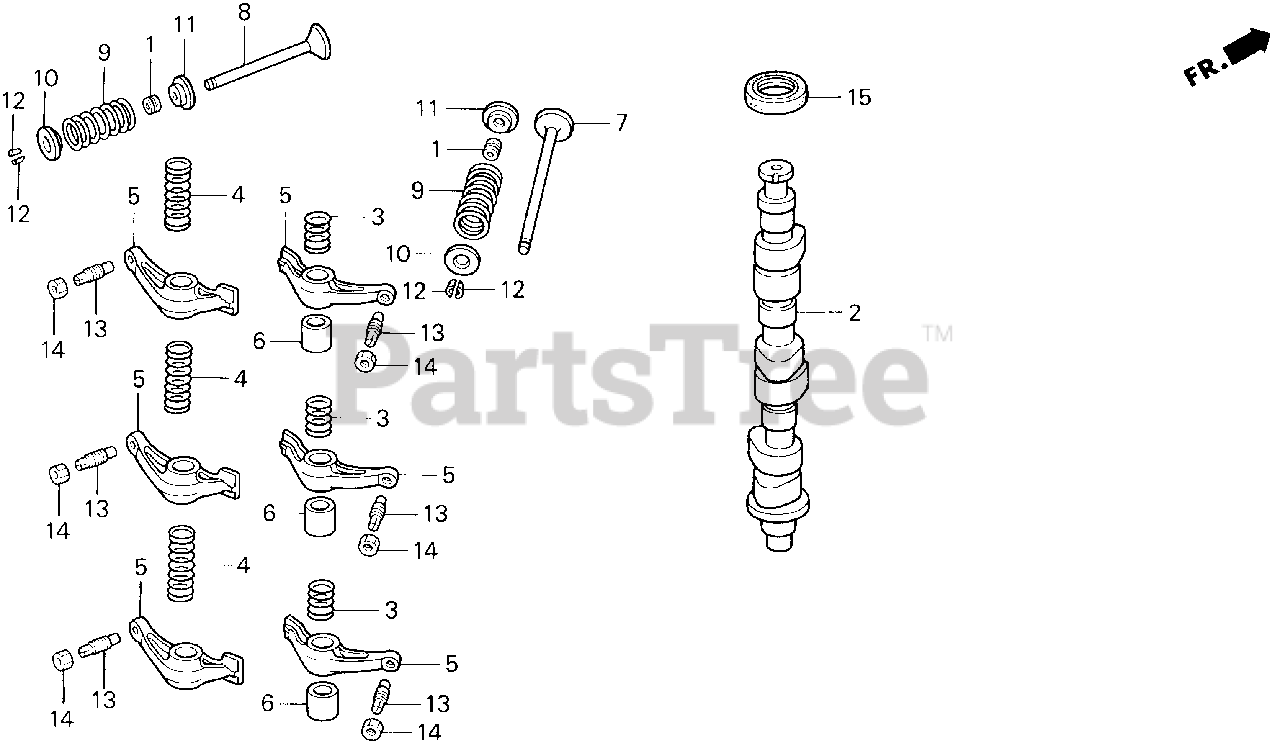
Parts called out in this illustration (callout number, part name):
1	SEAL, VALVE STEM
3	SPRING, ROCKER ARM A
4	SPRING, ROCKER ARM B
5	ARM, IN. ROCKER
6	COLLAR, ROCKER
7	VALVE, IN.
8	VALVE, EX.
9	SPRING, VALVE
9	SPRING, VALVE (CHUO SPRING)
10	RETAINER, VALVE SPRING
11	SEAT, VALVE SPRING
12	COTTER, VALVE
13	SCREW, TAPPET ADJUSTING
14	NUT, TAPPET ADJ.
15	OIL SEAL (30X42X8)
